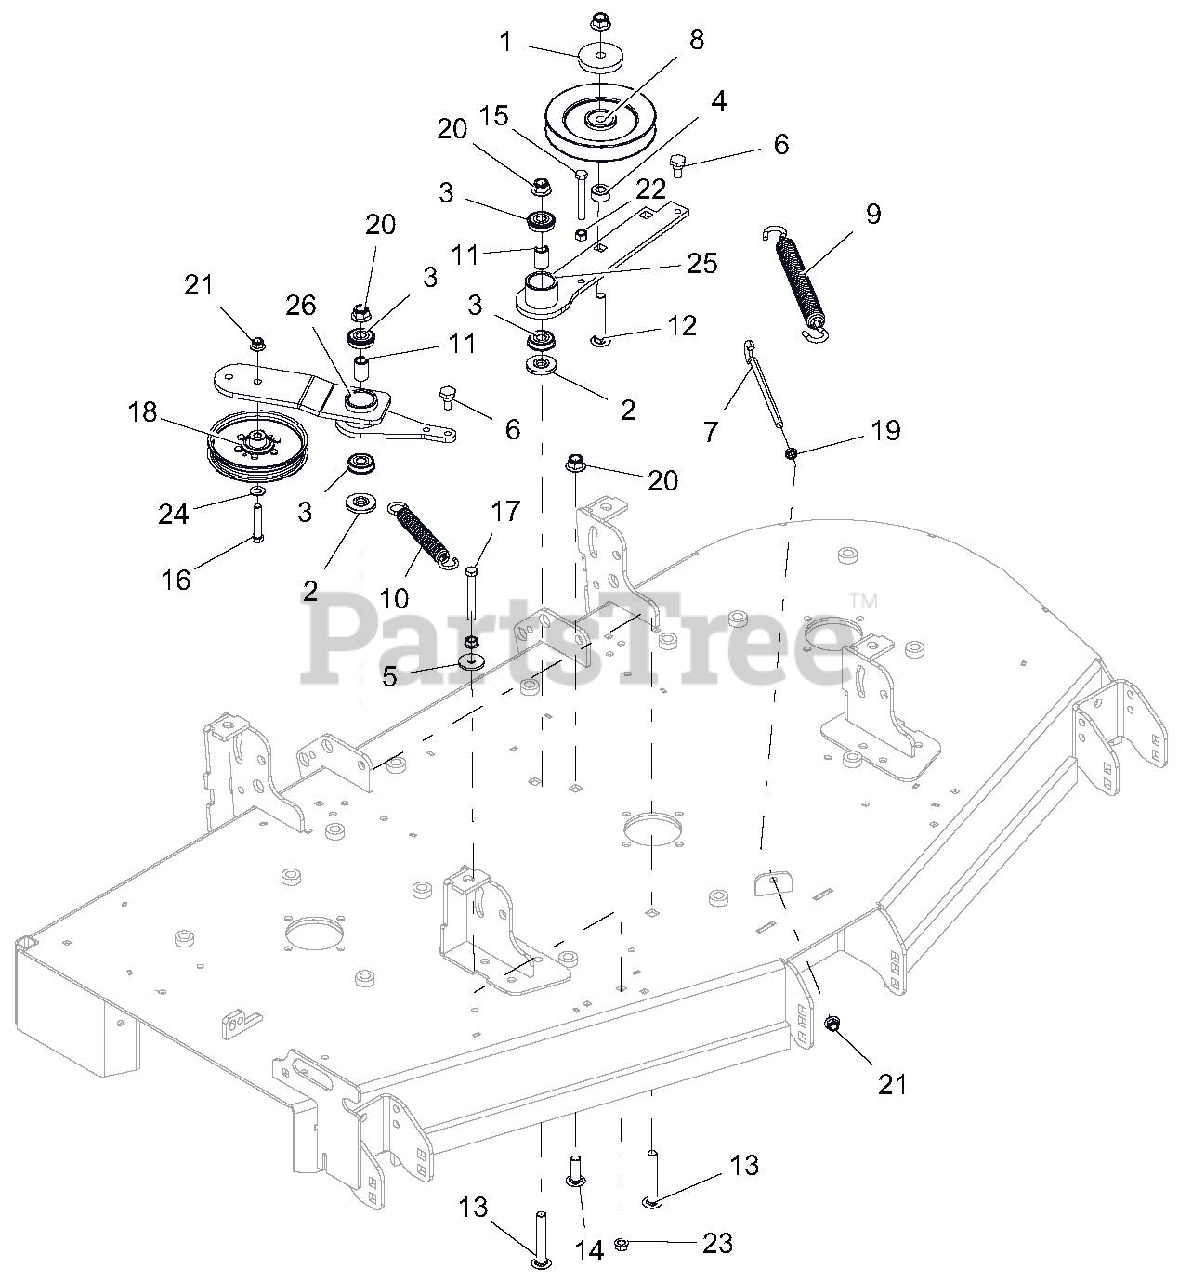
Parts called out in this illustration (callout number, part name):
1	CAP, IDLER BEARING SEALING
2	SPACER, IDLER ARM
3	BRG, BALL .501 X 1.38 X .438 SEALED
4	BSHG, SPCR .502 X .997.50 PM
5	WSHR-FL-STL .406X1.375X.135 YZ
6	BLT, SHLDR EP .38-16X.30 HEX YZ
7	BOLT, .38-16X6.00 .62 DIA EYE
8	SHEAVE, .50" ID X 6.00" OD V-IDLER
9	SPRG, EXTENSION
10	SPRG, EXTENSION
11	SPACER, .510 X .750 X 1.148
12	BLT-RDHDSQNK .50-13X3.00 G5 Y
13	BLT-RDHDSQSHNK .50-13X3.25 YWZC
14	BLT-RDHDSQSHNK .50-13X1.50 YWZC
15	BLT-HEX .38-16X2.75 GR5 YWZC
16	BLT-HEX .38-16X2.00 GR5 YWZC
17	BLT-HEX .38-16X3.00 GR5 YWZC
18	PULLEY, FLAT IDLER .500 X .375 W/BRG
19	NUT, JAM .375-16 YWZC
20	NUT-LK-NYL-FLG .50-13 YWZC
21	NUT-LK-NYL-FLG .38-16 YWZC
22	NUT-HEX .38-16 YWZC
23	@NUT-SPNLK-FLG .375-16 YWZC
24	WSHR-FL-STL.406X.812X.065 YWZ
25	WLDMT, DECK PTO IDLER ARM-BLACK
26	WLDMT, DECK RH IDLER ARM
